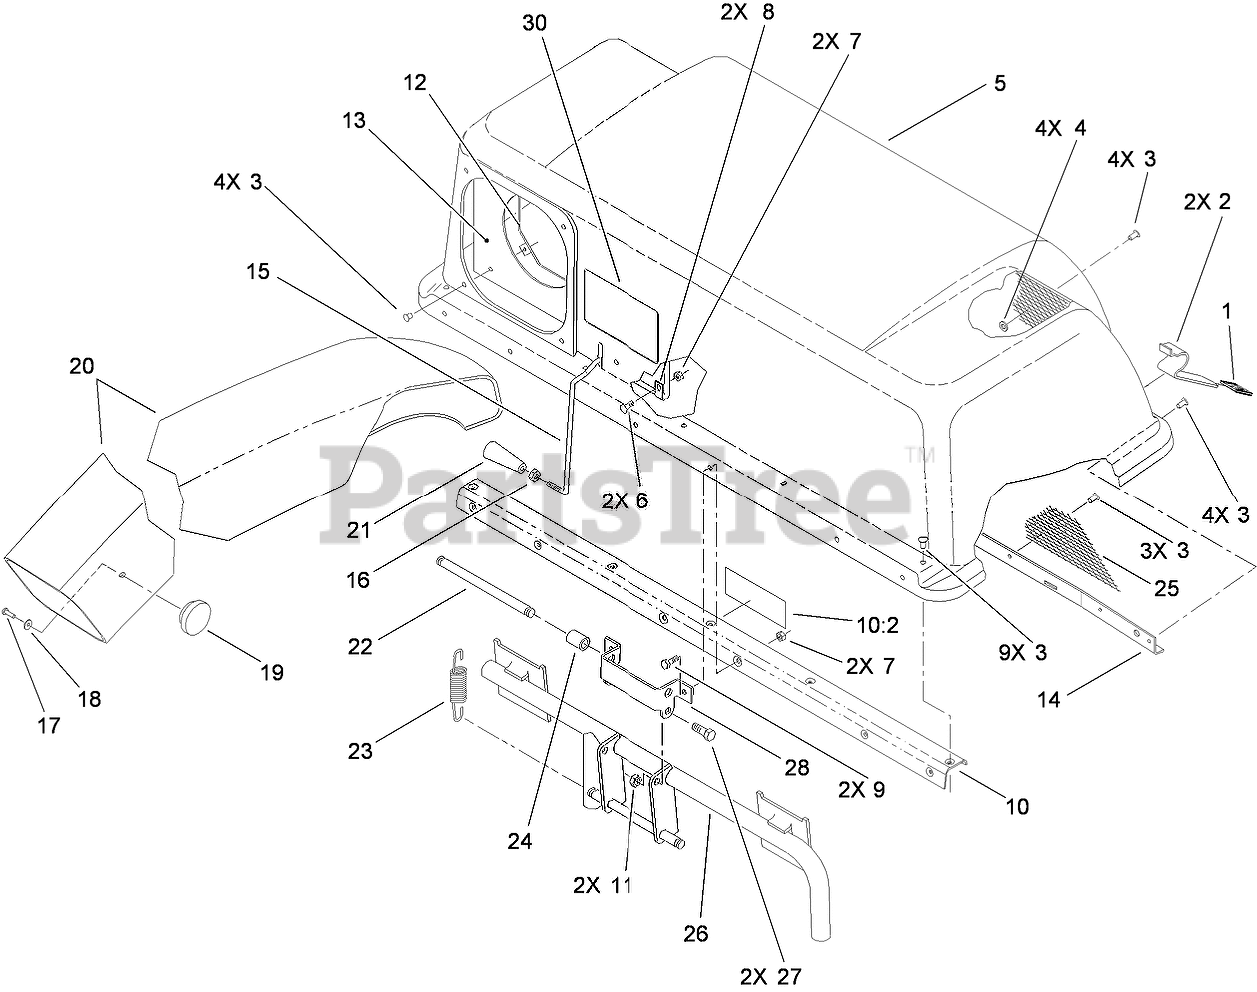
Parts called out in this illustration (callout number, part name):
2	LATCH-BAGGER, TOP
3	RIVET-BLIND
4	WASHER-FLAT
5	TOP-BAGGER
6	SCREW-HH
7	NUT-LOCK, NI
8	CLAMP
9	SCREW-HH
10	BAG STIFFENER ASM
10:2	DECAL-CAUTION
11	NUT-LOCK, NI
12	CLAMP-SEAL
13	SEAL-CHUTE
14	SUPPORT-SCREEN
15	FEELER-FILL, BAG
16	NUT-JAM
17	SCREW-PPHTF
18	WASHER-PLAIN
20	Chute-Discharge
21	HANDLE-TAPERED
22	PIN-SPRING
23	SPRING-EXTENSION
24	Spacer
25	SCREEN-BAGGER
26	FRAME ASM
27	SCREW-HH
28	Hinge-Bag, Top
30	DECAL
